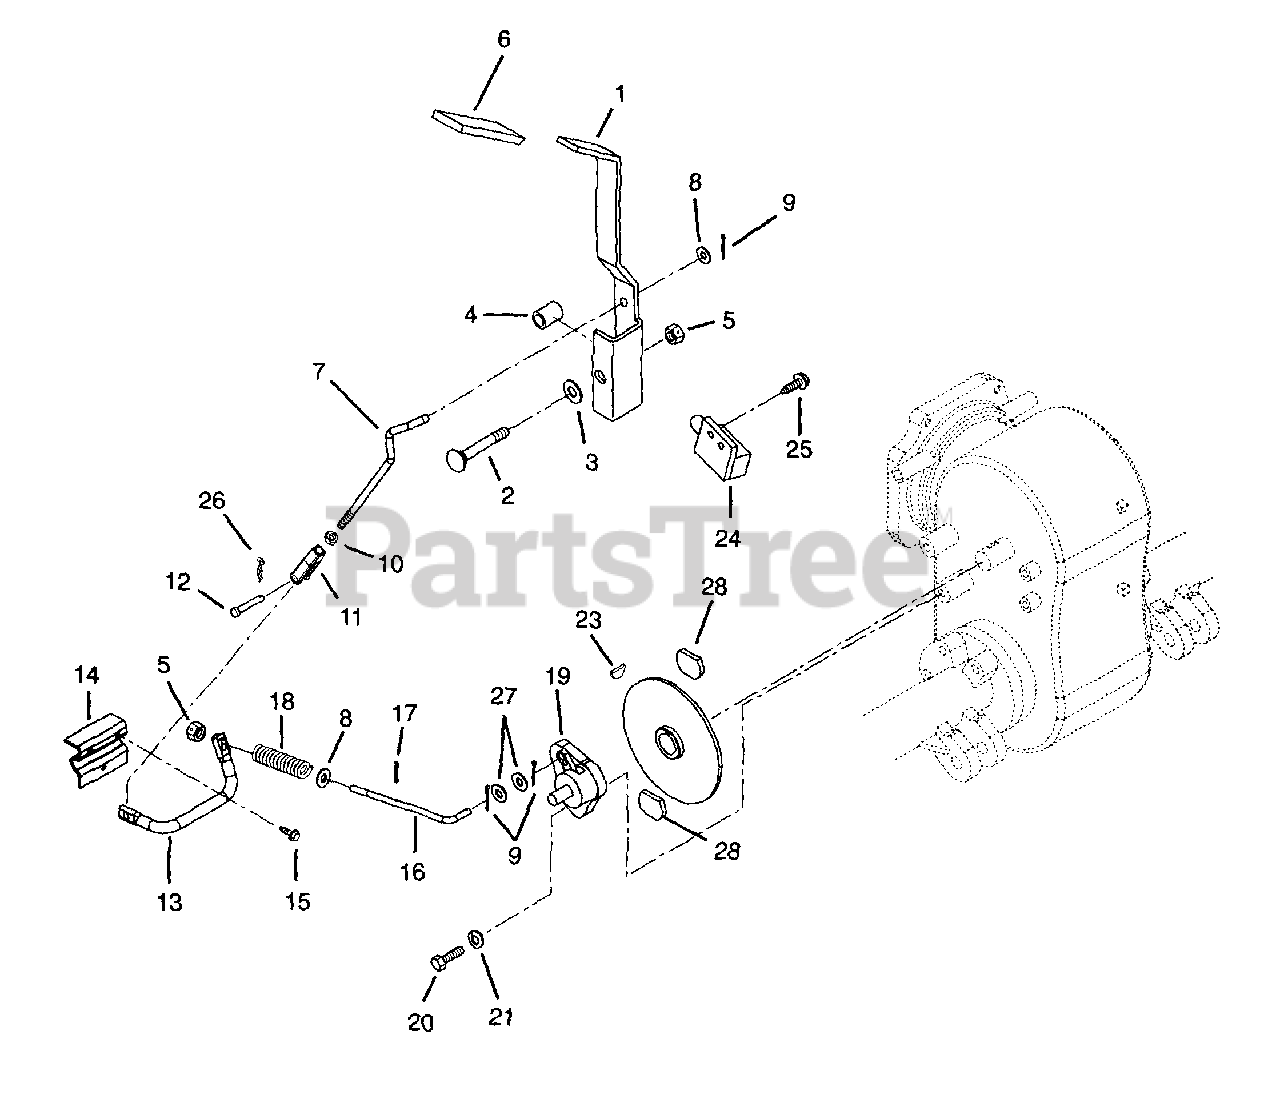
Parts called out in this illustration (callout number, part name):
1	Lever, Brake
2	Bolt-Round Head Square Neck .38-16 x 1.50
3	Washer-Flat-Steel .438 x 1.00 x .083
4	Spacer, Roll .41 ID x .62 OD x .42
5	Nut-Locking-Center .38-16
7	Rod, Brake Linkage
8	Washer-Flat-Steel .344 x .688 x .065
9	Pin-Cotter .12 x .75
10	Nut-Jam .31-24
11	Yoke .312-24 x 2.25
12	Pin-Clevis .31 x .937
13	Rod, Brake Pivot
14	Plate, Pivot
15	Screw-Tapping .250-20 x .75 Hex Washer Head
16	Rod, Brake Link
17	Roll Pin .156 x 1.00
18	Spring-Compression 2.00 x .404
19	Brake Assembly
20	Bolt-Hex .38-16 x 1.25 Grade 5
21	Washer-Locking .38 x .094
22	Weldment, Disk Brake
23	Key-Woodruff .188 x .75 x .313
24	Switch, Interlock N.C.
25	Screw-Tapping 12-24 x .50 Hex Washer Head
26	Pin-Hair-Internal .08 x .18 x 1.18
27	Washer-Flat-Steel .406 x .812 x .065
28	Pad, Brake
